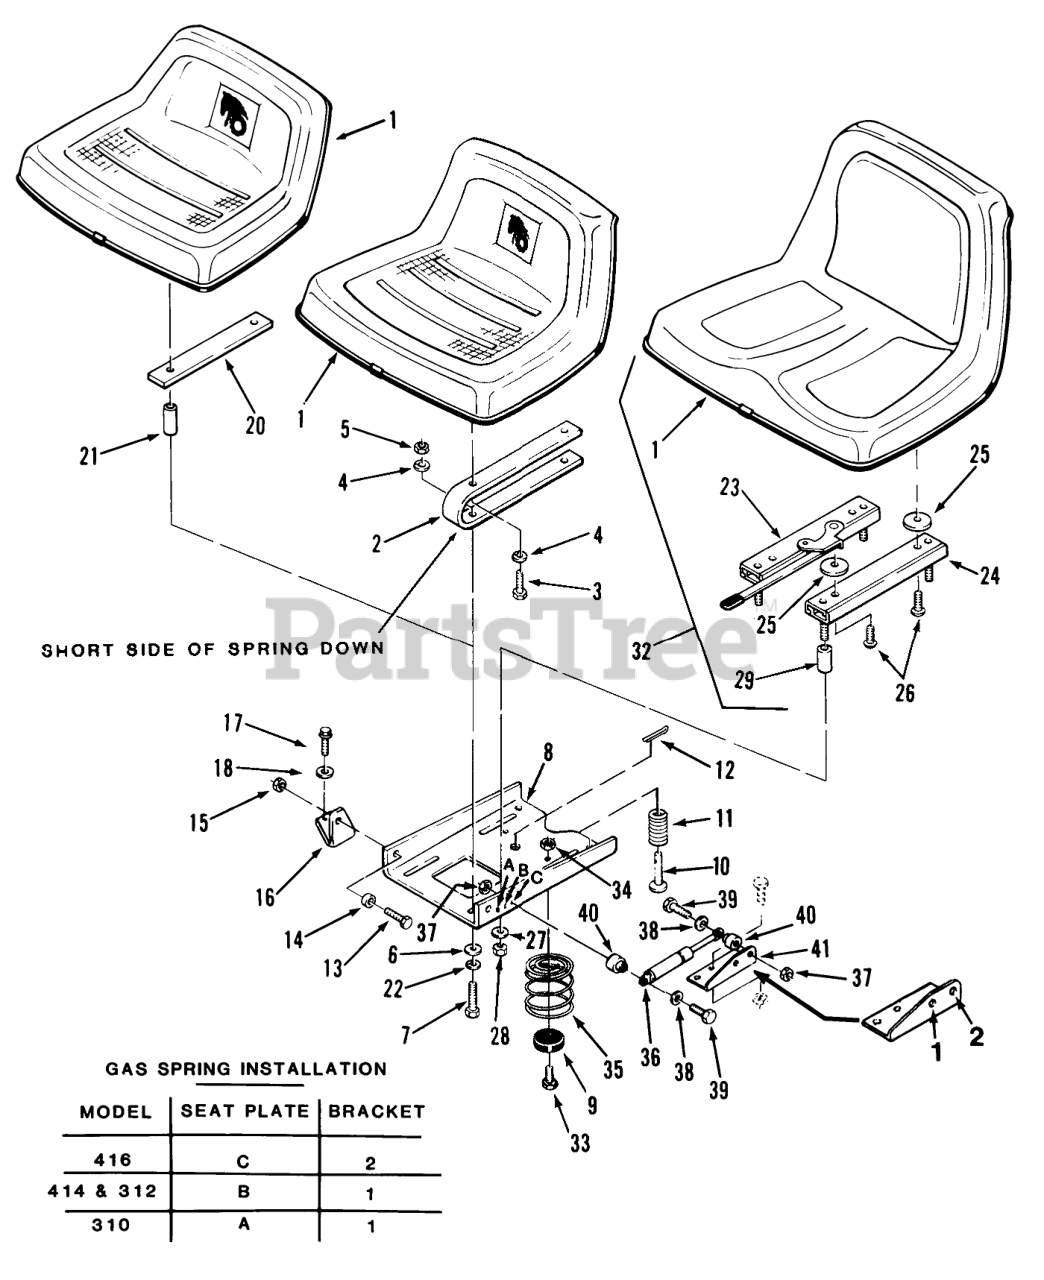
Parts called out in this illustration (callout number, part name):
1	Seat
2	Seat Spring
3	Bolt
4	Lockwasher
5	Nut
6	WASHER 5/16 SAE
7	HHCS
8	PLATE-SEAT PIVOT B
9	BUMPER
11	SPRING-SEAT SWITCH
12	Cotter Pin
13	HHCS
14	BUSHING
15	Nut
16	Bracket-Pivot RH
17	Bolt
18	WASHER 5/16 SAE
20	BAR SEAT SUPPORT B
21	SPACER SEAT B
22	Lockwasher
23	ADJUSTER-SEAT RH
24	ADJUSTER-SEAT LH
25	SPACER-NYLON
26	Screw
27	Collar
28	Nut
29	SPACER
30	RIVET
31	SPRING SWITCH
32	Deluxe Seat Assy (includes items 1, 23, 24, 25, 26 & 29)
33	Bolt
34	Nut
35	SPRING-SEAT NYLON
36	GAS SPRING
37	Nut
39	Bolt
40	SPACER
41	BRACKET-CYLINDER R
